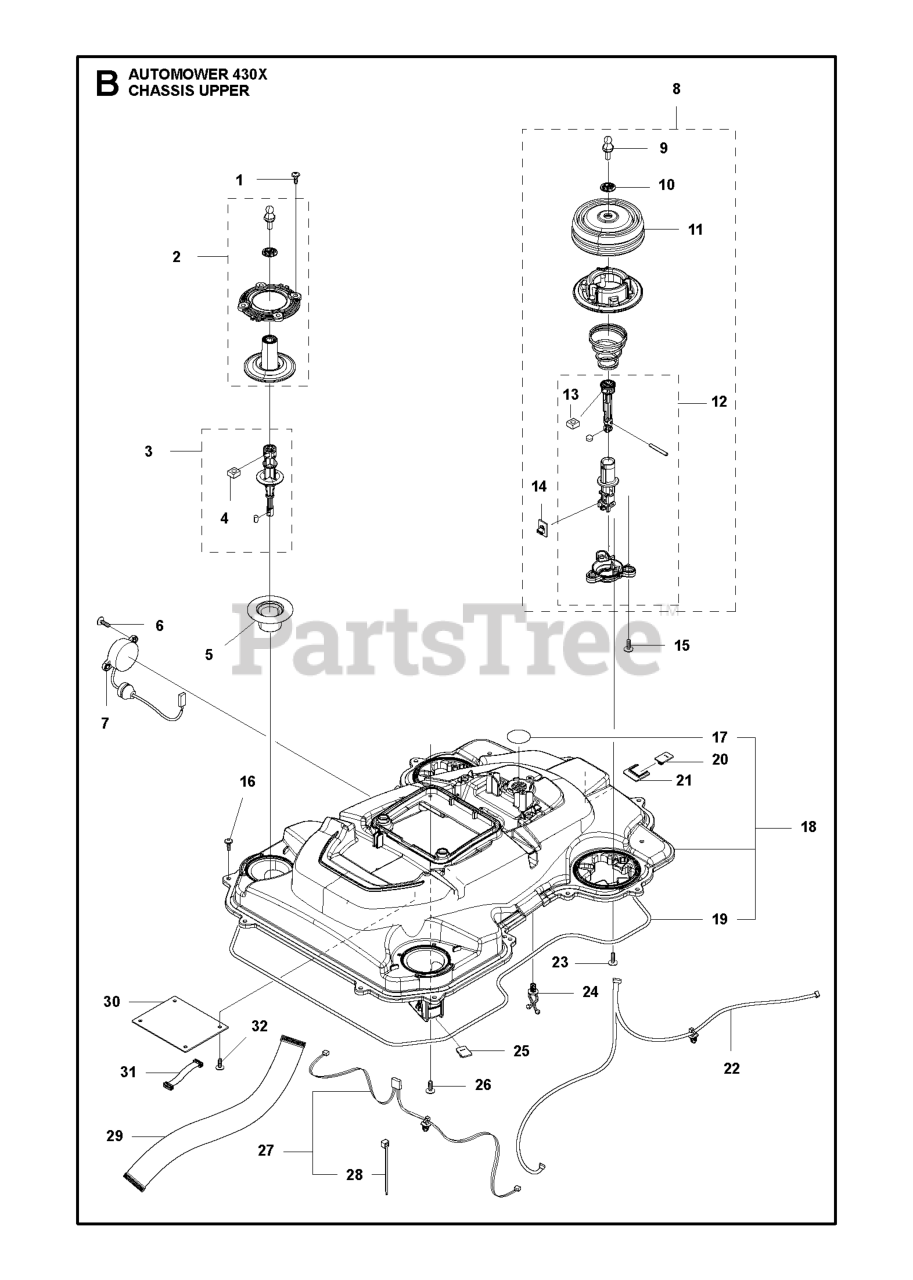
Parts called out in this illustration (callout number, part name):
2	DECAL.HOOD.NAMELOGO.HUSQ
4	DECAL, HOOD PANEL
5	DECAL HOOD CUST. RESP.
6	DECAL.REPLACEMENT.LTH1538.2007
7	DECAL.WHEEL.STRG.LGN.H
8	DECAL.ENG.BS15.5HP.INTEK.GEN
9	DECAL BTRY SYMBOLS
11	DECAL.WARN.KEEP.HAND.AWAY
12	DECAL.V-BELT.SCHEMATIC.36/38/9
13	DECAL.FEND.INS/WARN.HY
